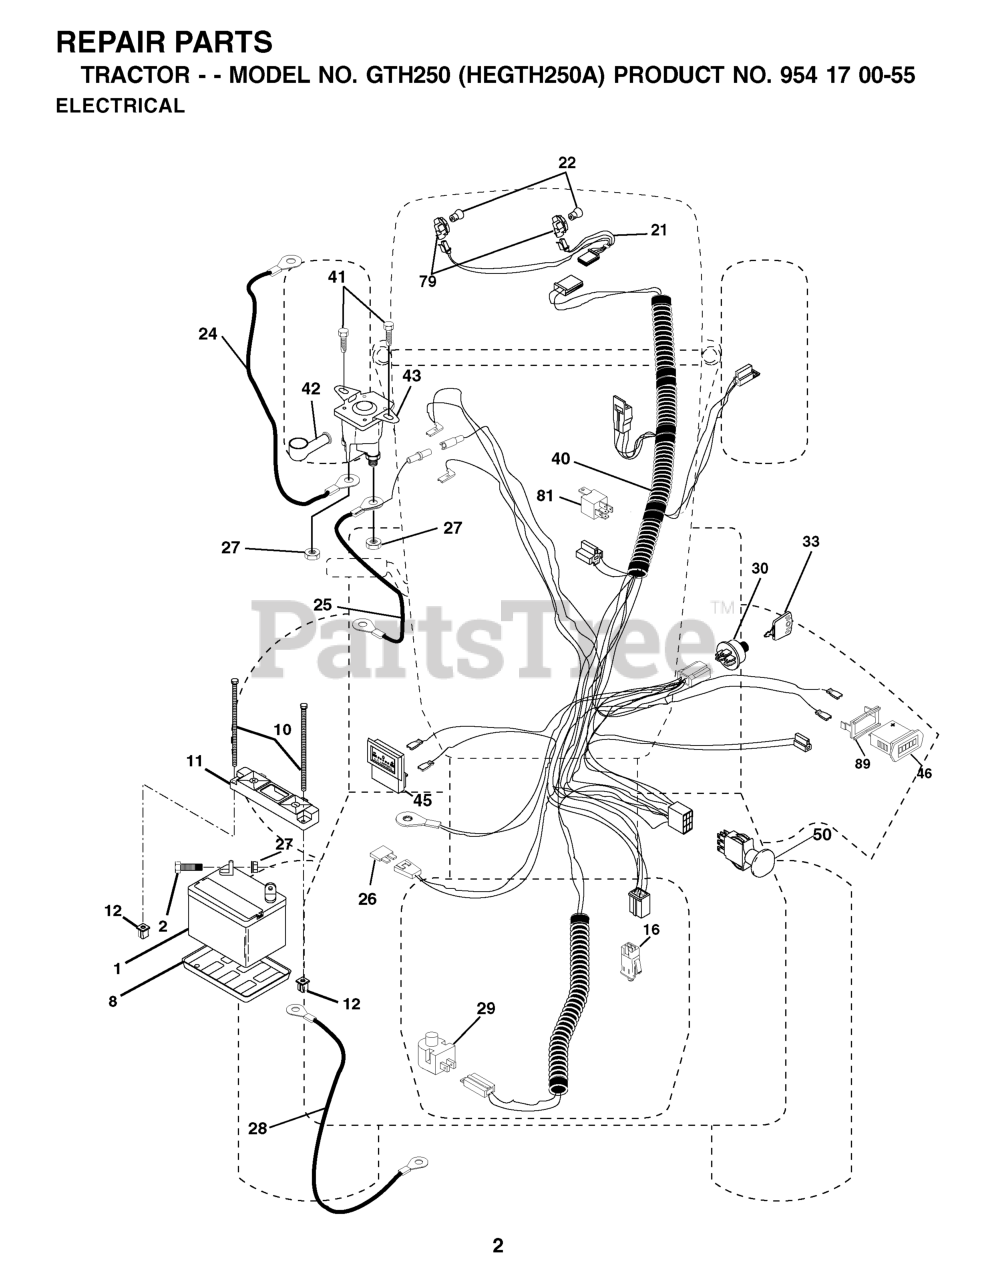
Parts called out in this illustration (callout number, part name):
1	BATTERY 12V .35 AMP
2	BOLT.HEX.1/4.X.3/4.DICHROMATE
8	BATTERY TRAY T
10	BOLT 1/4-20 X 7.5
11	BATTERY HOLDDOWN FRONT MOUNT
12	NUT, PUSH NYLON 1/4" BATTERY
16	SWITCH INTERLOOK PUSH-IN
21	HARNESS.W/LIGHT SOCKET
24	CABLE-BATTERY YTV
25	CABLE, BATTERY
27	NUT
28	CABLE, GROUND
29	PLUNGER SWITCH (COLOR:OLIVE)
30	IGNITION SWITCH
33	KEY MLD GEN DELTA
40	HARNESS, IGNITION
41	SCREW
42	TERMINAL COVER
43	SOLENOID
46	HOUR METER
50	RP.PTO.SWITCH.8 TERMINAL.BLACK
79	BULB HOLDER ASM.
81	RELAY.ASSY.T
89	BRACKET SNAP-IN HOURMETER
